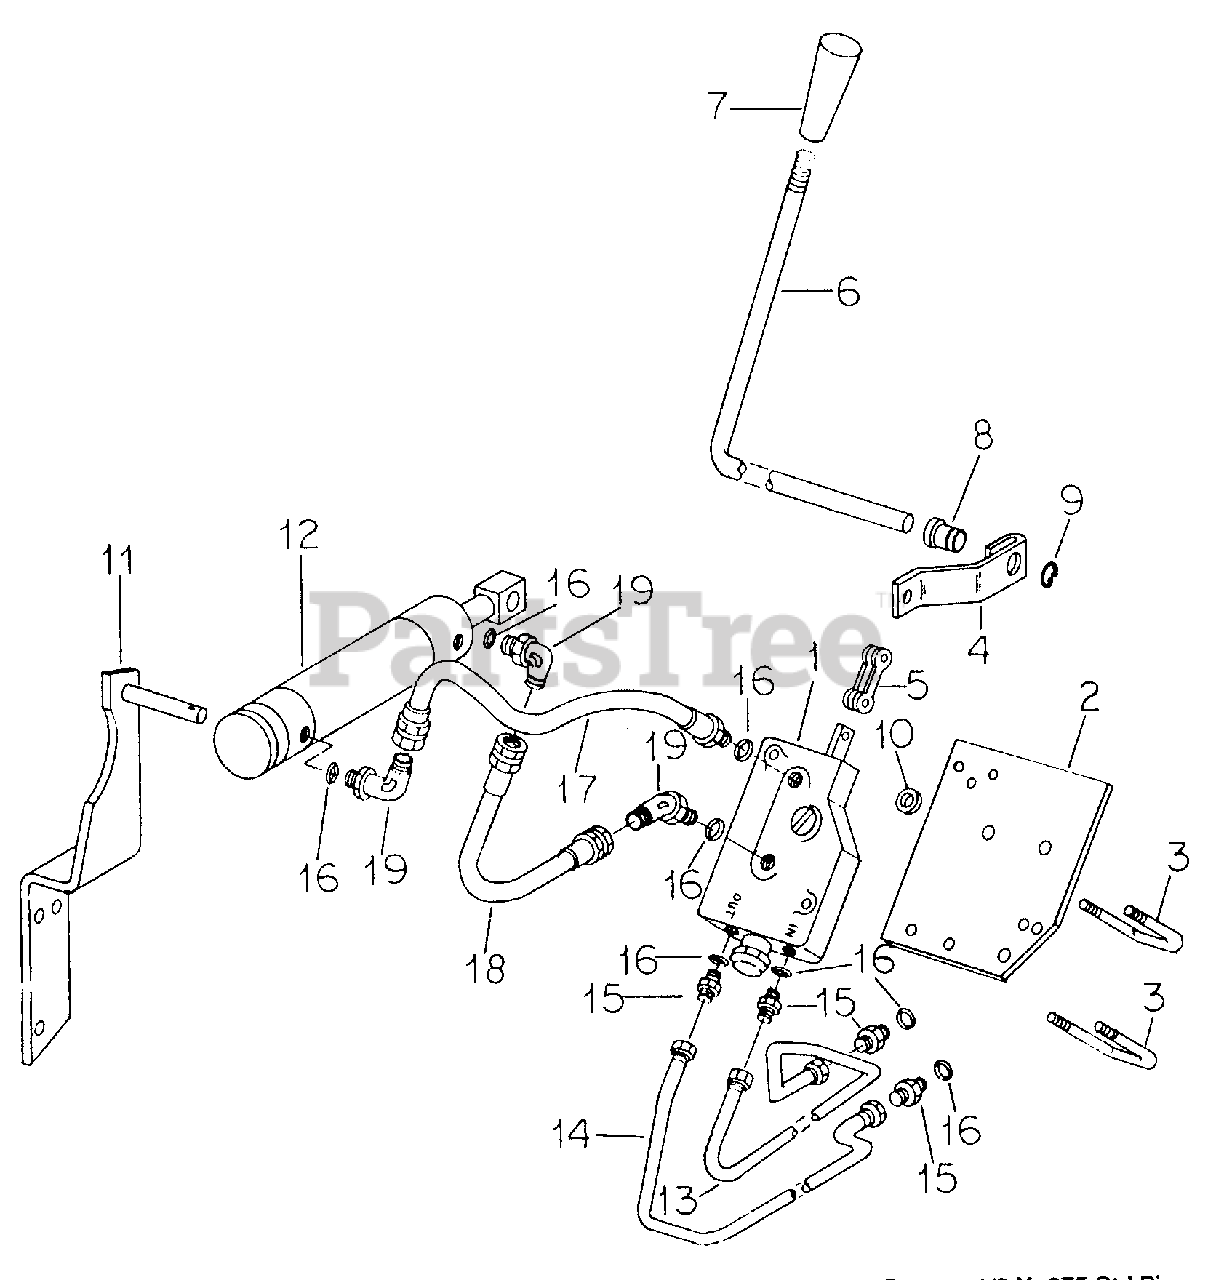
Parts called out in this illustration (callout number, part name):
1	Valve Assy, Control
2	Plate, Valve Support
4	Lever Assy, Valve Handle
5	Link, Chain
6	Handle, Valve
7	Grip, Handle
8	Bushing, Valve Handle
9	Ring, Retaining
10	Spacer, 1/8 X .375 Std Pipe
11	Bracket Assy, Lift
12	Cylinder Assy, Hydraulic Lift
13	Tube Assy, Pressure
14	Tube Assy, Return
15	Union, 9/16-18 C-Z 37 Deg Hyd Flared Tube Short Swivel
16	O-Ring, 3/8 OD Tube
19	Elbow, 9/16-18 C-Z 37 Deg Hyd Flared Tube Adj Str Thd 90 Deg
